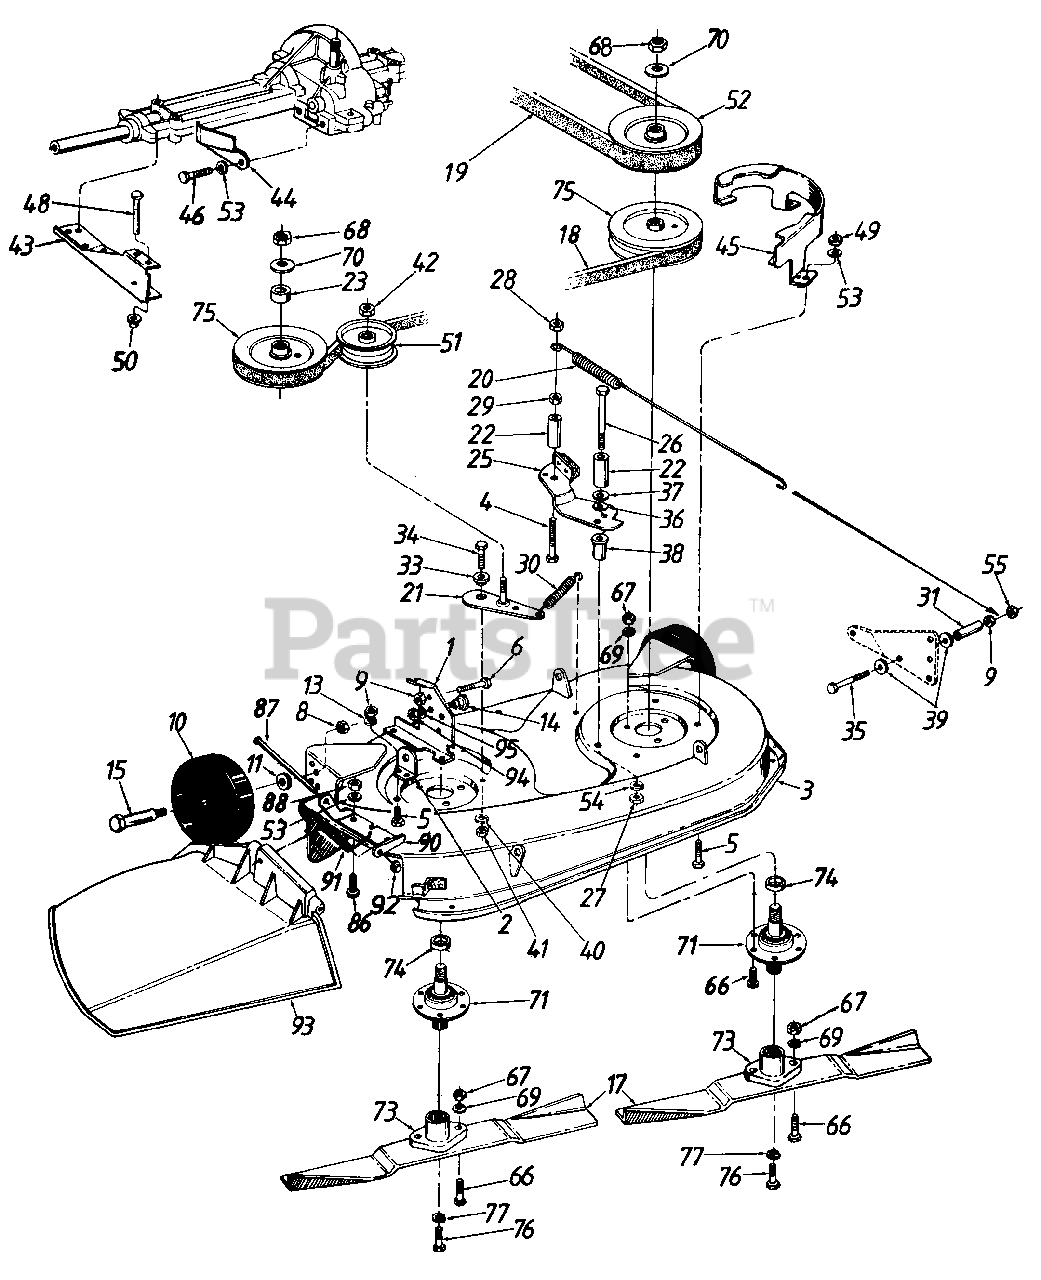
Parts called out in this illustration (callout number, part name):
1	Deck Engagement Brkt.
2	Rear Deck Brkt.-R.H.
3	32" Deck Ass'y.
4	Hex Bolt 1/4-28 x 1.75" Lg.
5	Hex Bolt 1/4-20 x .62" Lg.
6	Hex Wash. Hd. Scr. 1/4-20 x 1.5" Lg.
8	Hex L-Nut 3/8-16 Thd.
9	Hex Nut 1/4-20 Thd.
10	Deck Wheel
11	Bell-Wash. .38" I.D. x .88"
13	L-Wash. 1/4" I.D.
14	Shld. Bolt .500" Dia. x .336"
15	Shld. Bolt .498" Dia. x 1.53"
17	High-Lift Blade 3" x 16.28"
18	V-Belt
19	V-Belt
20	Extension Spring 15-5/8" Lg.
21	Idler Brkt. Ass'y.
22	Spacer 5/16" I.D. x 1/2" O.D. x 31/32"
23	Spacer .752" I.D. x 1.25" O.D.
25	Deck Brake Brkt. Ass'y.
26	Hex Bolt 5/16-18 x 3.25" Lg.
27	Hex Nut 5/16-24 Thd.
28	Hex L-Nut 1/4-28 Thd.
29	Hex Nut 1/4-28 Thd.
30	Extension Spring 4.35" Lg.
31	Spacer 1/4" I.D. x 3/8" O.D. x 1-5/16" Lg.
33	Shoulder Spacer
34	Hex Bolt 3/8-16 x 1" Lg.
35	Hex Bolt 1/4-20 x 2.5" Lg.
36	Wave Washer .53" l.D.
37	Shld. Spacer .51 " I.D. x .27"
38	Spacer .312" I.D. x 1.46" Lg.
39	Flat Wash. 1/4"
40	L-Wash. 3/8" l.D.
41	Hex Nut 3/8-16 Thd.
42	Hex L-Nut 3/8-24 Thd.
45	Belt Guard Deck-R.H.
46	Hex Bolt 1/4-20 X .6211 Lg.
48	Pin 1/4 Dia. x 2.5n Lg.
49	Hex Nut 1/4-20 Thd.
50	Cap Speed Nut 1/4" Rod
51	Flat Idler Pulley
52	5n Dia. Pulley
53	Bell-Wash..265" I.D.
54	Bell-Wash. 5/16" l.D.
55	Hex L-Nut 1/4-20 Thd.
66	Hex Bolt 5/16-24 x 1" Lg.
67	Hex Nut 5/16-24 Thd.
68	Hex Jam Nut 5/8-18 Thd.
69	L-Wash. 5/16" I.D.*
70	Bell-Wash. 5/8" I.D.
71	Blade Spindle Ass'y. Comp.
73	Blade Adapter
75	5n Dia. Pulley
76	Hex Bolt 3/8-24 x 1.0" Lg.
77	L-Wash. 3/8" l.D. H.D.
86	Hex Bolt 1/4-20 X .62" Lg.
87	Hinge Pin
88	Hex Nut 1/4-20 Thd.
90	Hinge Mtg. Brkt.
91	Torsion Spring
92	Cap Speed Nut 1/4" Rod
93	Chute Ass'y. Comp.
94	Hex Nut 3/8-16 Thd.
95	L-Wash. 3/8" l.D.
